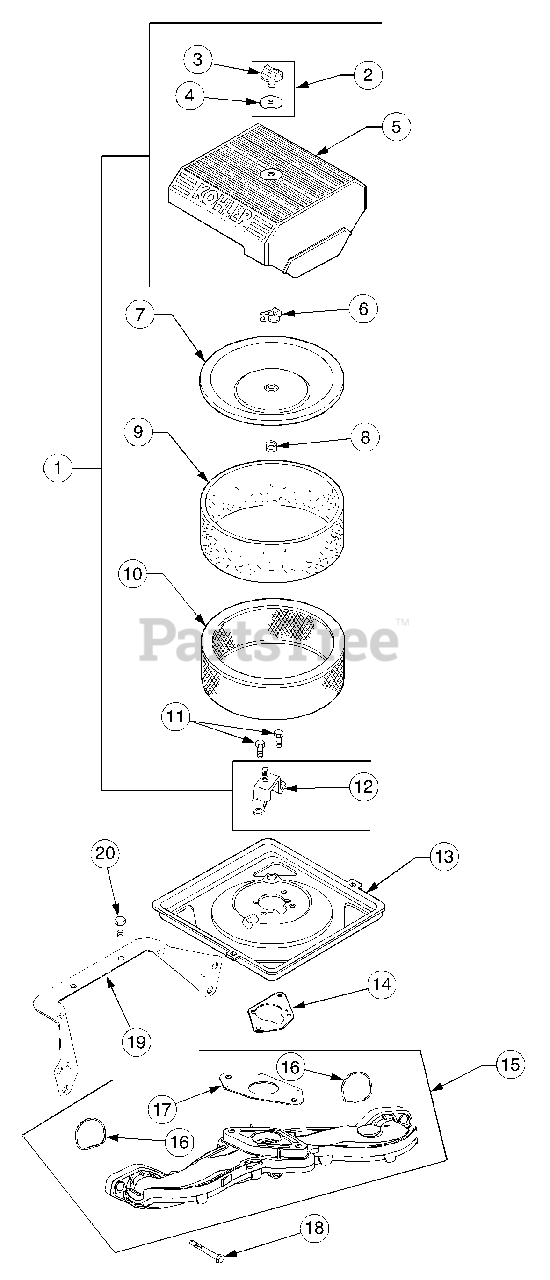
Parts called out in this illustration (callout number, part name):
1	Kit, Air Cleaner Cover
2	Kit, Knob w/Seal
3	Knob, Cover
4	Seal, Air Cleaner Cover Knob
5	Cover, Air Cleaner
7	Cover, Inner Air Cleaner
8	Seal, Inner Air Cleaner
9	Precleaner, Element
10	Element, Air Cleaner
11	Screw, Hex Flange, M6 x 1.0 x 16
12	Bracket, Air Cleaner Base
13	Base, Air Cleaner
14	Gasket, Air Cleaner Base
15	Manifold, Intake
16	O-Ring, Intake Manifold
17	Gasket, Carburetor
18	Screw, Hex Flange, M6 x 1.0 x 40
19	Bracket, Air Cleaner Base
20	Screw, Hex Flng, M5 x 0.8 x 10
